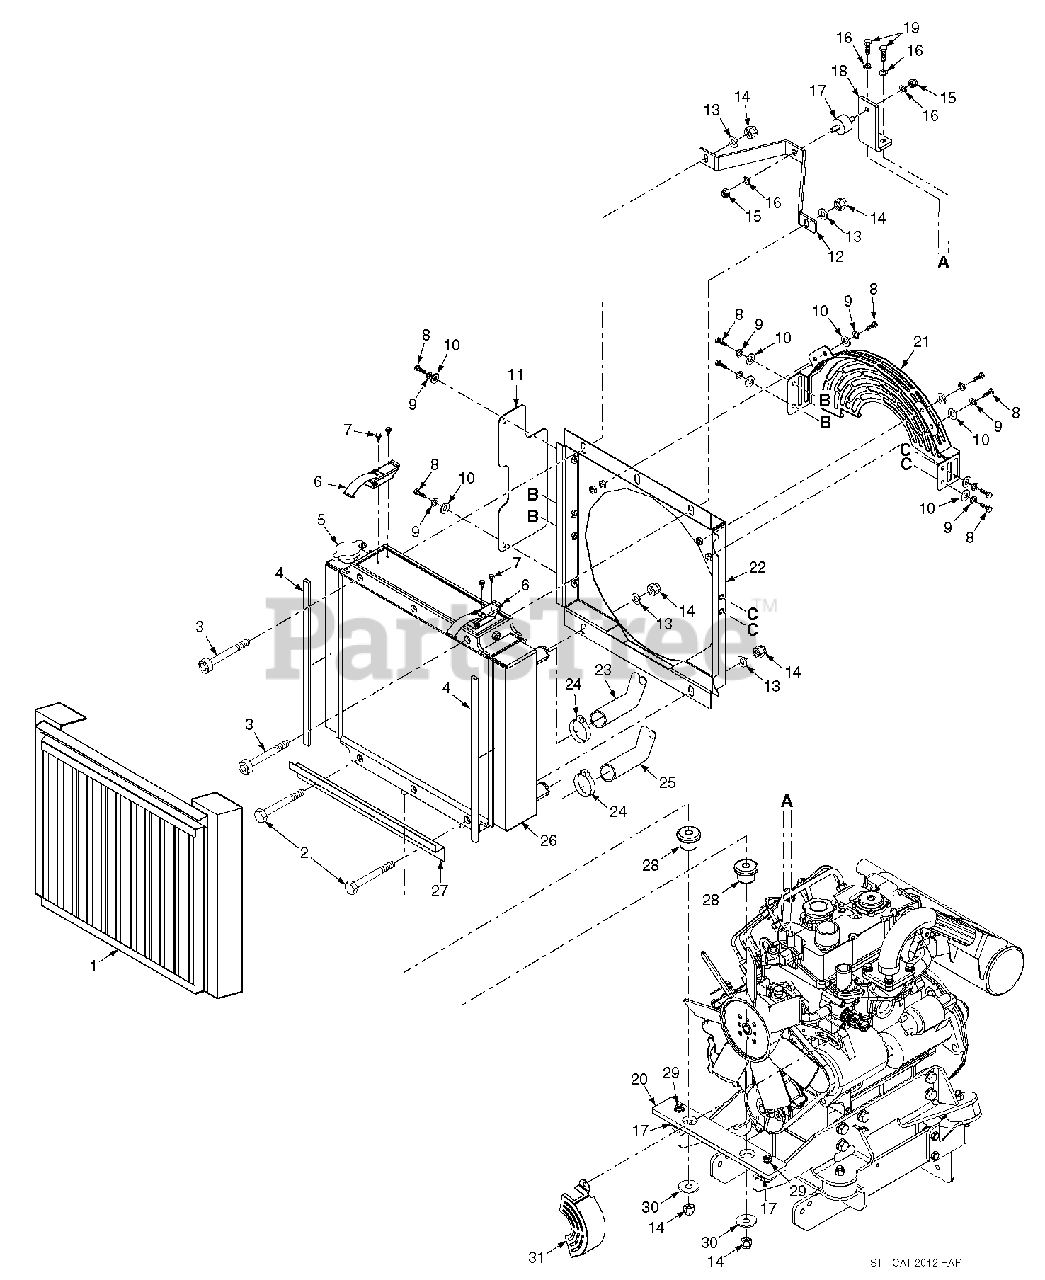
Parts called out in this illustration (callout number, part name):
1	Debris Screen Weldment
2	Bolt, Hex Head 3/8-16 x 4-1/2"
3	Bolt, Socket Head 3/8-16 x 4-1/2"
4	Foam, Seal, 1/2" x 1/4" x 14-1/2"
5	Radiator Cap
6	Latch, Hood
7	Screw, #10-32 x .56
8	Bolt, Hex Head 1/4-20 x .63"
9	Lockwasher, 1/4" Spring
10	Flatwasher, 1/4"
11	Heatshield
12	Bracket, Radiator Support
13	Flatwasher, 3/8"
14	Nut, Elastic Stop 3/8-16
15	Nut, 5/16-18
16	Lockwasher, 5/16"
17	Mount, Radiator Isolation
18	Bracket, Radiator Mount to Engine
19	Bolt, Hex Head M8 x 1.25 x 25
20	Mount, Radiator
21	Guard, Fan
22	Shroud Weldment, Radiator
23	Hose, Upper Radiator
24	Clamp, Hose, 1-3/4"
25	Hose, Lower Radiator
26	Radiator
27	Support, Debris Screen
28	Mount, Radiator Isolation
29	Nut, Hex Serrated Flange 5/16-18
30	Flatwasher, 3/8"
31	Guard, Belt
